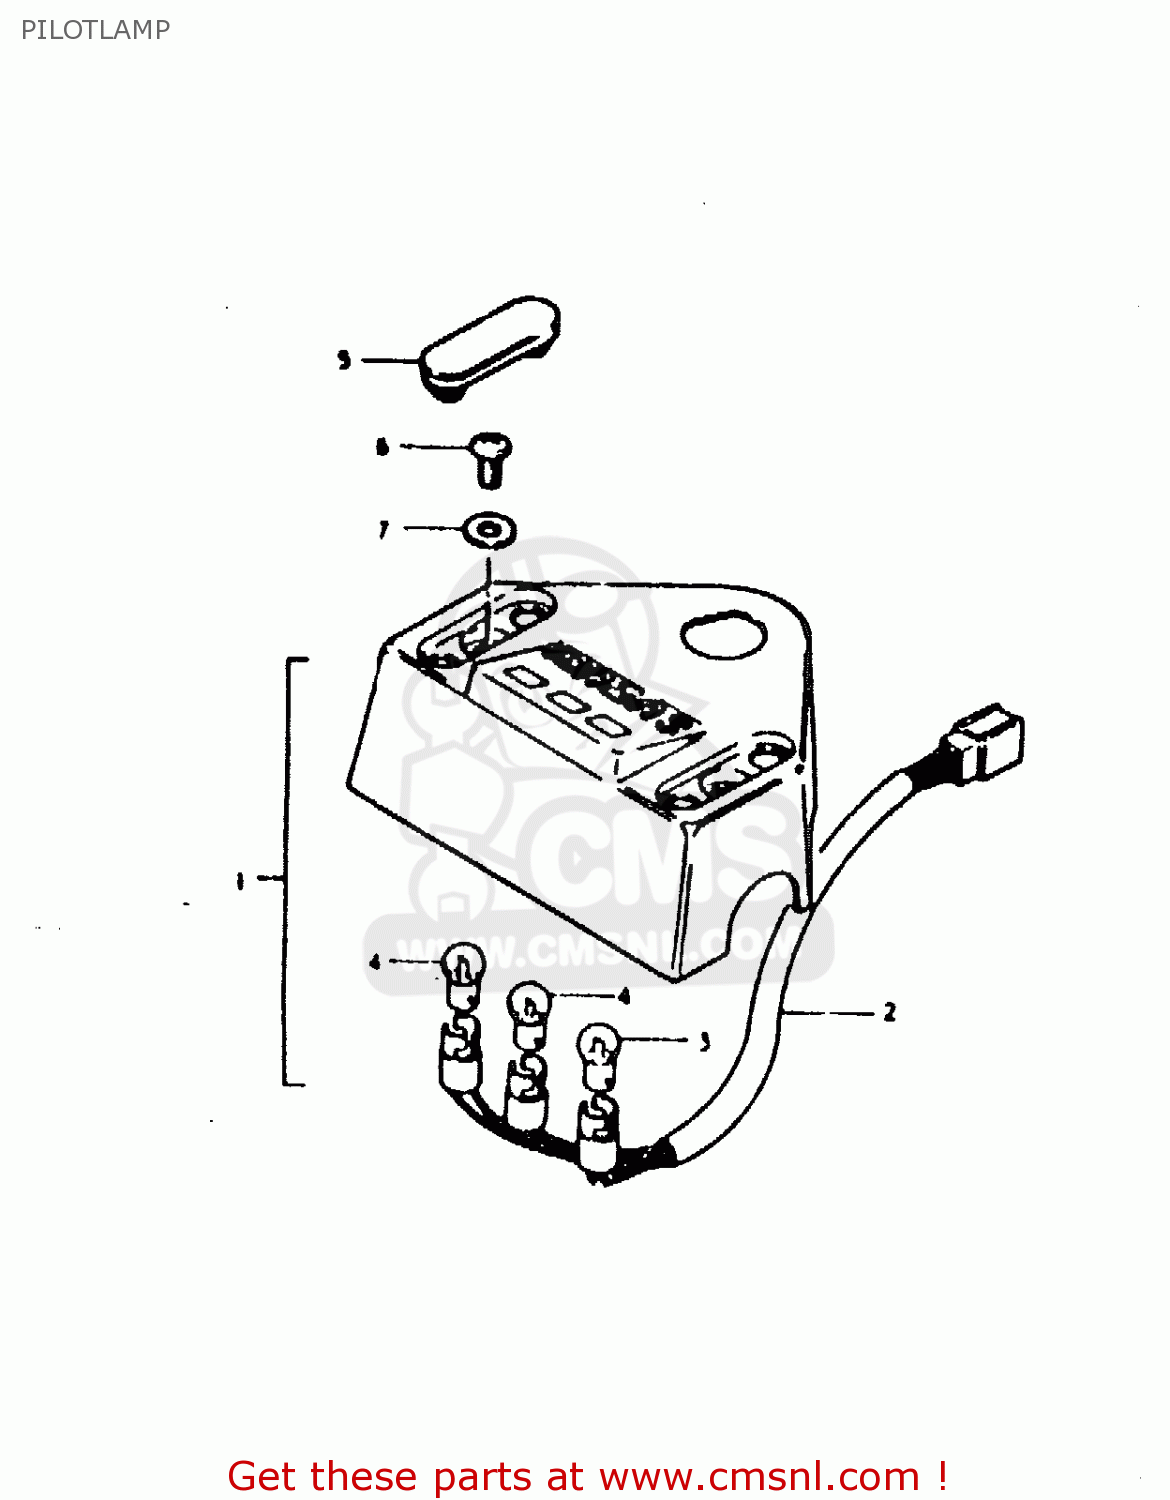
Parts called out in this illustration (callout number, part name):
1	CASE,PILOT BULB
2	SOCKET
3	BULB(6V1.7W,STANLEY,A61A)
4	BULB(6V/3W)
5	CAP,PILOT BOX BOLT
6	SCREW 6X12
7	WASHER
